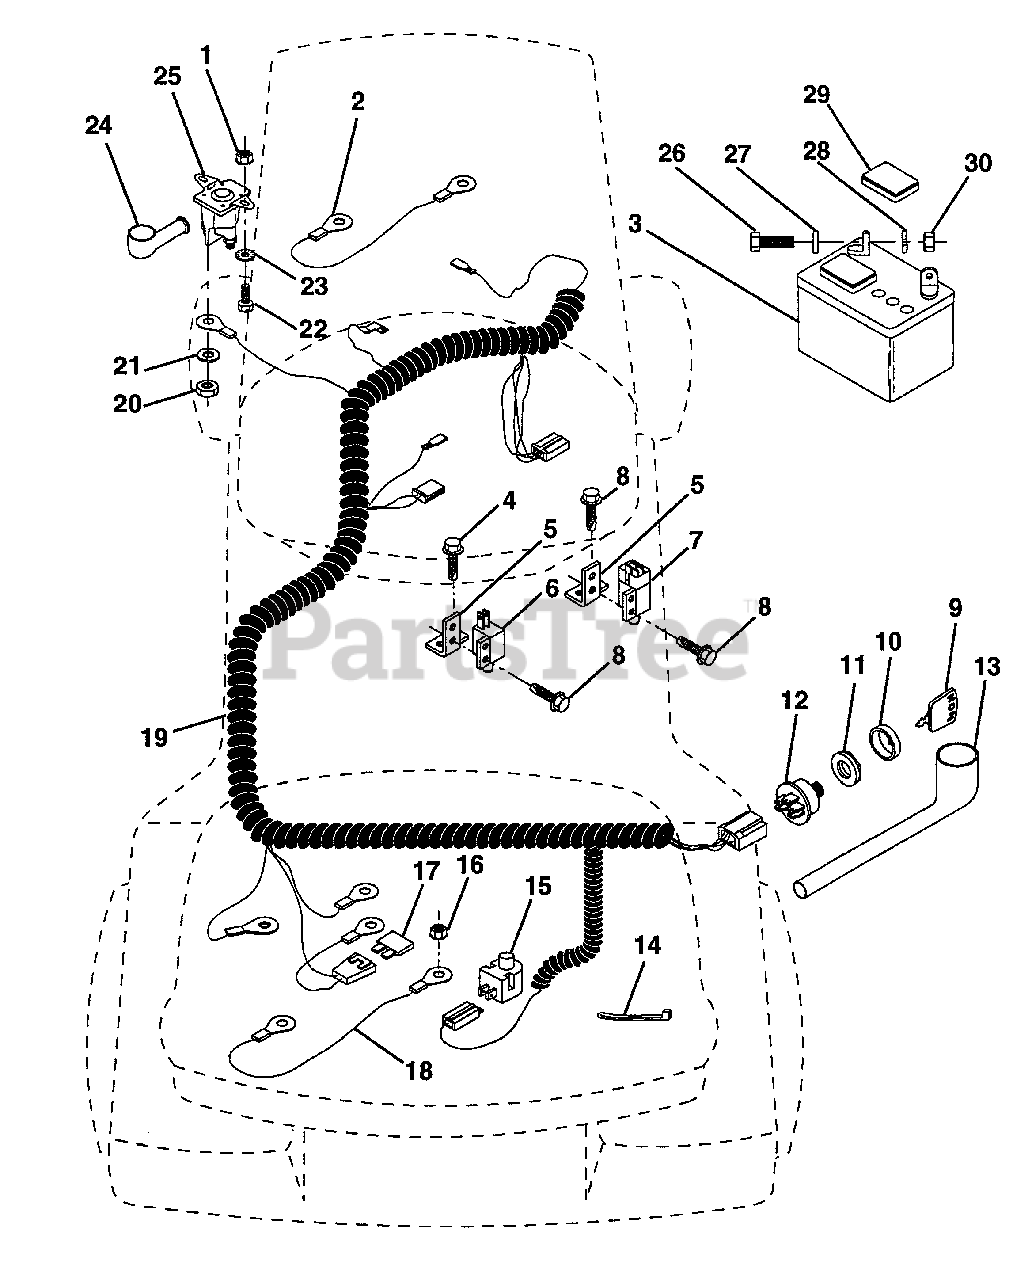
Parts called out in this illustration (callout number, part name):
1	Nut, Hex Keps 1/4-20
2	Assembly, Cable
3	Battery
4	Screw, Hex Wsh. Tap #10-16 x 1/2
5	Bracket, Switch
6	Switch, Interlock
7	Switch, Interlock
8	Screw, Hex Hd. Tap #10-24 x 1/2
9	Key, Molded
10	Cover, Key Ignition
11	Nut, Ignition
12	Switch, Ignition
13	Cover, Ignition Switch
14	Tie, Cable
15	Switch, Plunger
16	Nut, Hex, Keps 5/16-18
18	Assembly, Cable
19	Harness, Ignition
20	Nut, Hex Jam 1/4-20
21	Washer, Lock 1/4
22	Bolt, Fin Hex 1/4-20 UNC x 1/2 Gr. 5
23	Washer, Lock Ext. Tooth 1/4
24	Cover, Terminal
25	Solenoid
26	Bolt, Hex Hd. 1/4-20 UNC x 3/4
27	Washer 9/32 x 5/8 x 16
28	Washer, Lock 1/4
29	Cap, Battery
30	Nut, Fin Hex 1/4-20 UNC
